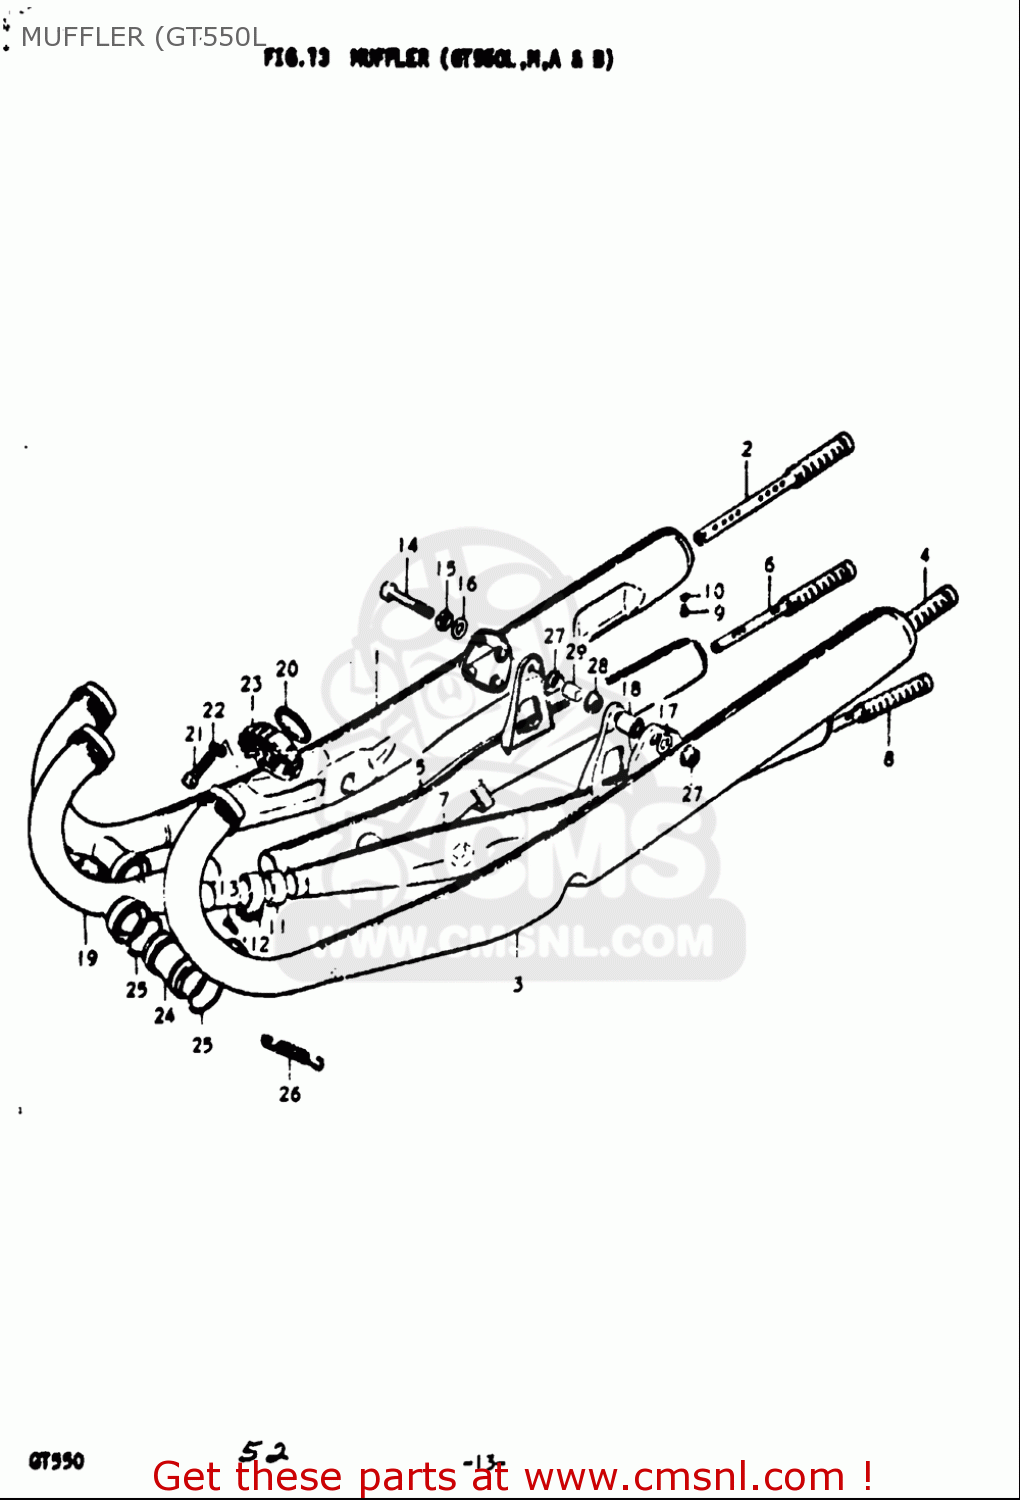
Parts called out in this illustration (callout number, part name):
2	PIPE,BAFFLE
4	PIPE,BAFFLE
6	PIPE,BAFFLE
8	PIPE,BAFFLE
9	BOLT(5X8)
10	WASHER,LOCK
11	CONNECTOR,MUFFLER
12	CLAMP
13	SCREW
14	BOLT
15	WASHER,LOCK
16	WASHER
17	WASHER
18	BUSHING(10X23X35)
20	GASKET,EXHAUST PIPE (NAS)
21	BOLT
22	WASHER,LOCK
25	O RING(D:2.6,ID:39.7)
26	SPRING
27	DAMPER,MUFFLER SUPPORT BRACKET
28	NUT (M10X1.25X9)
29	SPACER(10.1X15X4.8)
